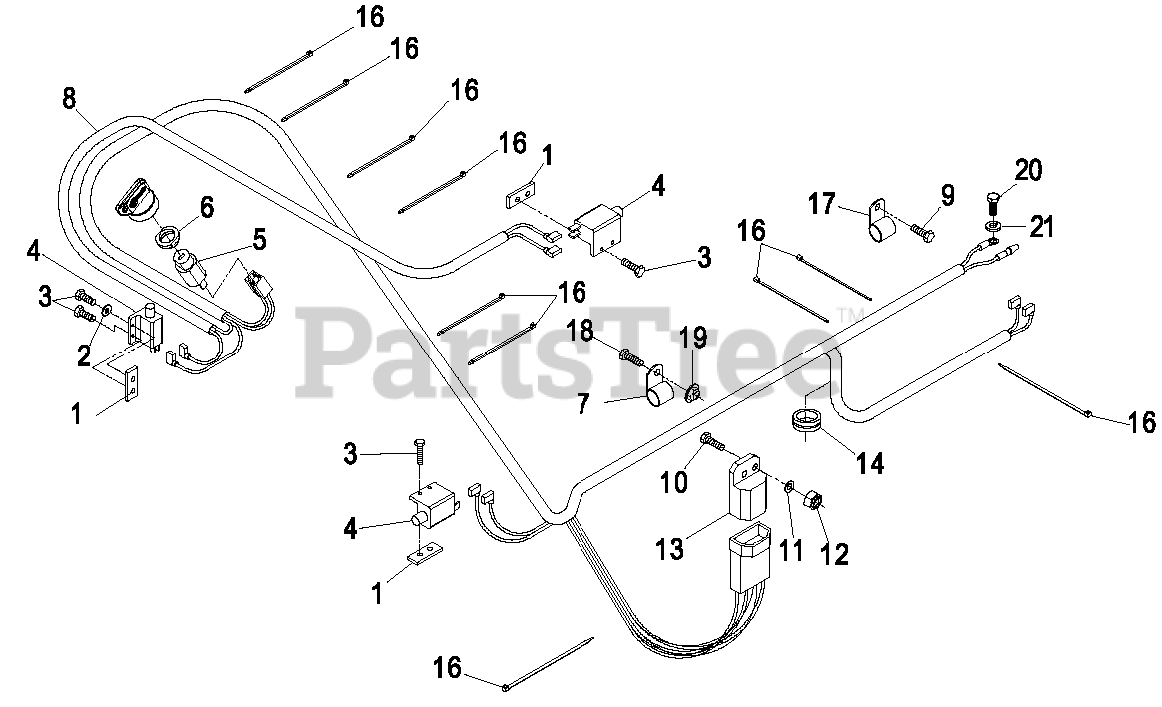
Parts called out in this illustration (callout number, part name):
1	PLATE-TAPPED
2	WASHER-FLAT
3	SCREW-PPH
4	SWITCH-OPEN, NORMALLY
5	SWITCH & KEY (INCLUDES NU
6	NUT-SWITCH, IGNITION
7	CLIP-LOOM
8	HARNESS-WIRING
9	SCREW-HH
10	SCREW-HH
11	WASHER-FLAT
12	NUT-LOCK, NI
13	MODULE-INTERLOCK
14	GROMMET
16	TIE-CABLE
17	CLIP-LOOM
18	SCREW-HH
20	SCREW-HH
21	WASHER-LOCK
